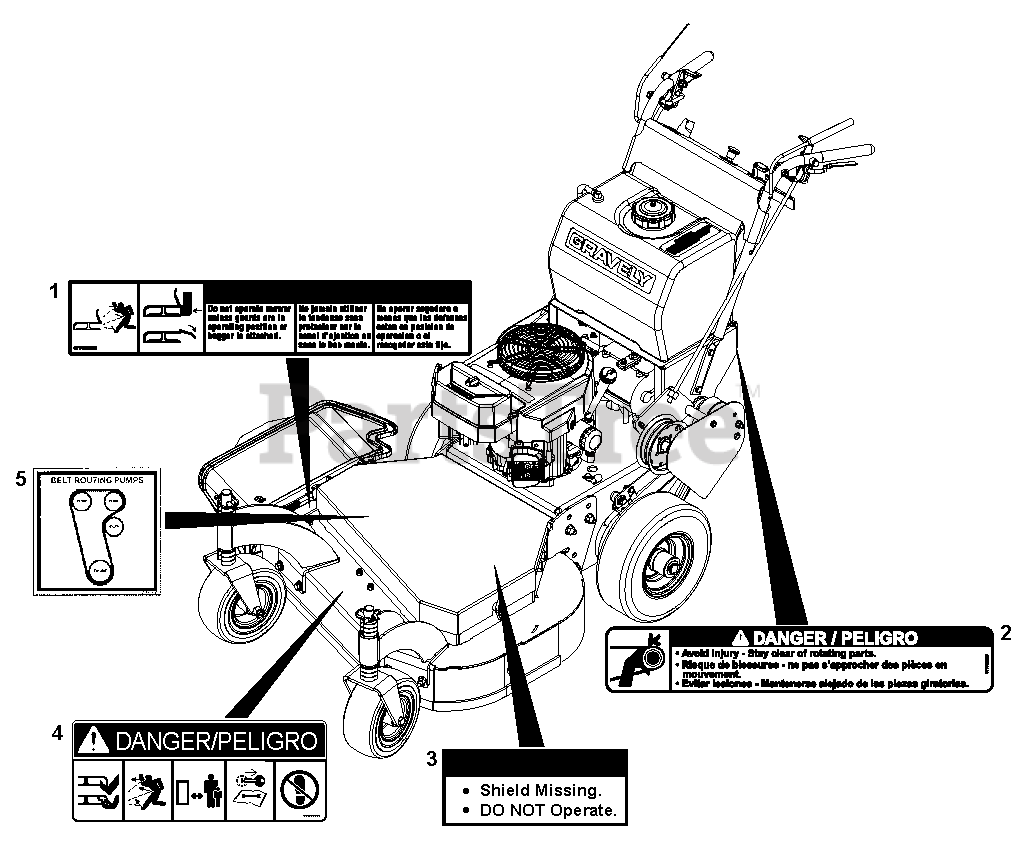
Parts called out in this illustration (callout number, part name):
1	Decal, Warning
2	Decal, Danger-Belt Rotating
3	Decal, Warning-Shield
4	Decal, Mower Pan Danger
5	Decal, Deck Belt Routing (143, 144)
